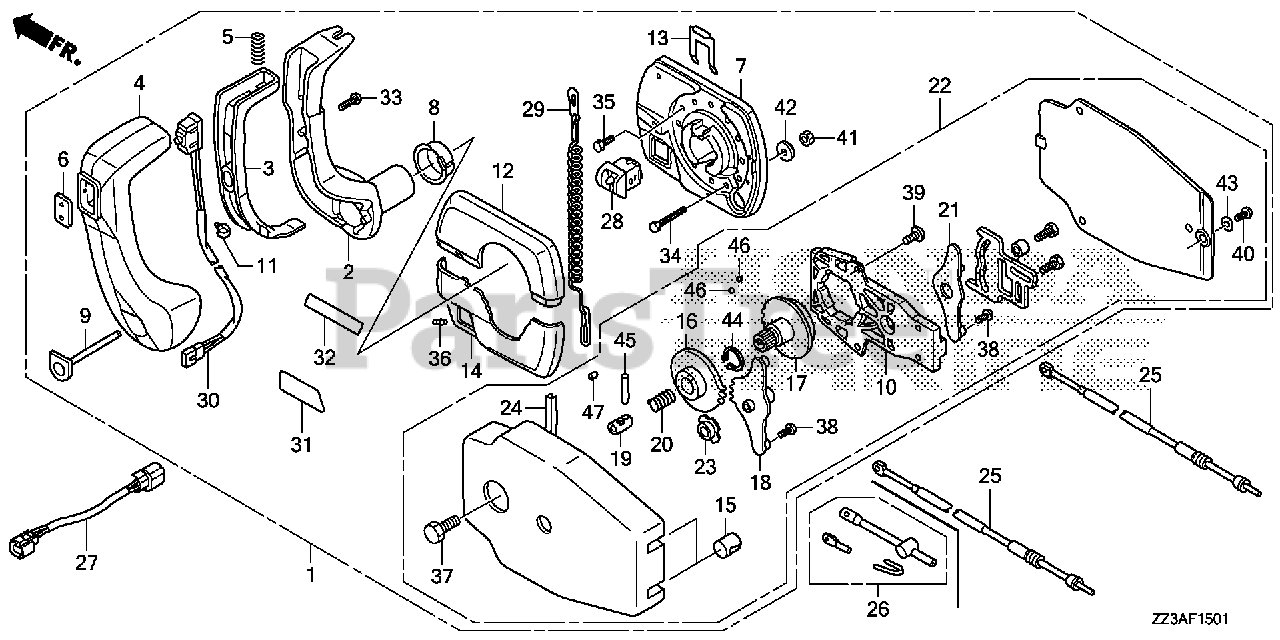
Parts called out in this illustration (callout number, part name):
1	BOX ASSY., REMOTE CONTROL (PANEL MOUNT) (NA USE ALT:06240-ZW7-U00)
2	HANDLE, REMOTE CONTROL
3	LEVER, HANDLE LOCK
4	GRIP, REMOTE CONTROL HANDLE
5	SPRING, REMOTE CONTROL HANDLE
6	COVER, GRIP
7	HOUSING ASSY., REMOTE CONTROL BOX (A)
8	BUSHING
9	BUTTON, THROTTLE
10	FRAME ASSY., REMOTE CONTROL BOX
11	BAND B, CABLE
12	HOUSING, REMOTE CONTROL BOX (B)
13	RETAINER
14	HOUSING, REMOTE CONTROL BOX (C)
15	GROMMET
16	WHEEL, CONTROL
17	SHAFT, HANDLE (NOT AVAILABLE)
18	ARM ASSY., SHIFT LINK
19	SHAFT, GEARSHIFT
20	SPRING, GEARSHIFT
21	ARM ASSY., THROTTLE LINK
22	HOUSING ASSY. (INNER) (PANEL MOUNT)
23	BUSH
24	SPRING
25	CABLE, REMOTE CONTROL (10') (TELEFLEX)
25	CABLE, REMOTE CONTROL (10') (BRUNSWICK)
25	CABLE, REMOTE CONTROL (11') (TELEFLEX)
25	CABLE, REMOTE CONTROL (11') (BRUNSWICK) (NOT AVAILABLE)
25	CABLE, REMOTE CONTROL (12') (TELEFLEX)
25	CABLE, REMOTE CONTROL (12') (BRUNSWICK) (NOT AVAILABLE)
25	CABLE, REMOTE CONTROL (13') (TELEFLEX)
25	CABLE, REMOTE CONTROL (13') (BRUNSWICK) (NOT AVAILABLE)
25	CABLE, REMOTE CONTROL (14') (TELEFLEX)
25	CABLE, REMOTE CONTROL (14') (BRUNSWICK) (NOT AVAILABLE)
25	CABLE, REMOTE CONTROL (15') (TELEFLEX)
25	CABLE, REMOTE CONTROL (15') (BRUNSWICK) (NOT AVAILABLE)
25	CABLE, REMOTE CONTROL (16') (TELEFLEX)
25	CABLE, REMOTE CONTROL (16') (BRUNSWICK) (NOT AVAILABLE)
25	CABLE, REMOTE CONTROL (17') (TELEFLEX)
25	CABLE, REMOTE CONTROL (17') (BRUNSWICK) (NOT AVAILABLE)
25	CABLE, REMOTE CONTROL (18') (TELEFLEX)
25	CABLE, REMOTE CONTROL (18') (BRUNSWICK) (NOT AVAILABLE)
25	CABLE, REMOTE CONTROL (19') (TELEFLEX)
25	CABLE, REMOTE CONTROL (19') (BRUNSWICK) (NOT AVAILABLE)
25	CABLE, REMOTE CONTROL (20') (TELEFLEX)
25	CABLE, REMOTE CONTROL (20') (BRUNSWICK) (NOT AVAILABLE) (ALT. PNO: 24920-ZW1-003AH)
26	ADAPTER, REMOCON CABLE (N/A: USE 24931-ZW1-000)
27	HARNESS ASSY., POWER TRIM-TILT
28	SWITCH ASSY., EMERGENCY STOP
29	WIRE, EMERGENCY
30	SWITCH ASSY., POWER TRIM-TILT (A)
31	MARK, REMOTE CONTROL (A)(PANEL)
32	MARK, REMOTE CONTROL (B)(FOR STARBOARD)
32	MARK, REMOTE CONTROL (C)(FOR PORT)
33	SCREW A (NOT AVAILABLE)
34	SCREW B
35	SCREW C
36	SCREW SET (1/4-20X16")
37	BOLT
38	SCREW (8-32X3/8)
39	SCREW (10-32X5/8)
40	SCREW (10-32X5/8)
41	NUT (1/4X20)
42	WASHER
43	WASHER
44	CIRCLIP (OUTER)
45	PIN, GEARSHIFT
46	BALL, STEEL
47	ROLLER, SHIFT CLICK
